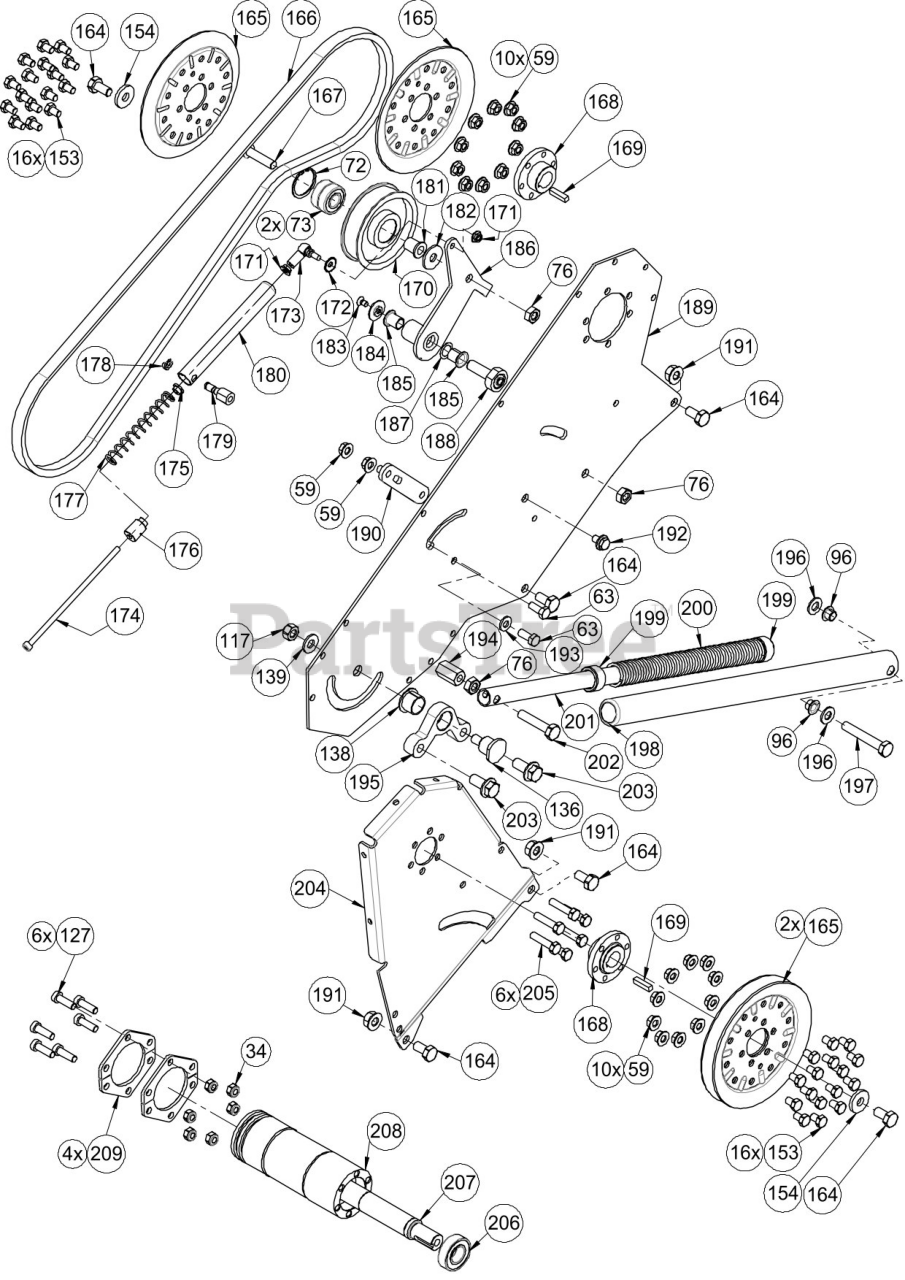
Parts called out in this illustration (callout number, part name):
34	NUT, LK-NYL M8 DIN 985 8 ZCC
59	NUT, FLG SLF LK M8 CL 8 ZCC
63	BLT, HEX M8X20 DIN 933 8.8
72	RG, RTNG-INT .35X1.5 DIN 472
73	BRG,BALL 6202-2RSH (15X35X11)
76	NUT, HEX M10 DIN 934 8 ZCC
96	BHSG, DU FLG BB1009DU
117	NUT, LK V-M10 DIN 980
127	TORX SHCS M8X25 SIMILAR TO DIN 7984 8.8
136	SCREW, COLLAR
138	BHSG, DU FLG BB201DU
139	WHSR, BLVL M10 DIN 6796
153	BLT, HEX M8X12 DIN 933 8.8 ZCC
154	WSHR, FLT M10.5 DIN 6340 ZCC
164	BLT, HEX M10X20 DIN 933 8.8 ZCC
165	HALF, PULLEY
166	V-BELT, PTO - INTERMEDIATE
167	SCR, BHC M10X40 ISO 7380
168	HUB, PULLEY
169	KEY, 6MM SQ X 25MM
170	PULLEY, IDLER
171	NUT, FLG M6 DIN 6923 8 ZCC
172	WSHR, LK EDGE F M6
173	JOINT, BALL
174	SCR, SKH M6X160 8.8 ZCC
175	BSHG, DU FLG BB 061006
176	GUIDE, COMP. SPRING
177	SPRING, COMPRESSION
178	RETAINER, KL 8 MBO 09
179	FOLLOWER, LONG
180	SLEEVE, SPRING
181	BUSHING, SLEEVE
182	WSHR, FLT M10.5 DIN 9021 ZCC
183	TORX FHCS M6X10 8.8 ZCC
184	WASHER, SPECIAL
185	BSHG, DU FLG BB 1207 DU
186	ASSY, IDLER ARM
187	WSHR, FLT M14 DIN 988
188	SPACER, IDLER MOUNT
189	PLATE, IDLER MOUNT
190	LEVER, SPRING TENSION
191	NUT, FLG SLF LK M10 CL 8 ZCC
192	BLT, SER FLG M8X12 VERBUS RIPP BK
193	WSHR, FLT M8.4 DIN 134 ZCC
194	NUT, COUPLING M10 DIN 6334 ZCC
195	BRKT, PIVOT
196	WSHR, FLT A M10.5 DIN 125 ZCC
197	BLT, HEX M10X65 DIN 931 10.9 (BLK)
198	SLEEVE, SPRING
199	GUIDE, SPRING
200	SPRING, COMPRESSION
201	TUBE, SPRING
202	BLT, HEX M10X50 DIN 931 8.8 ZCC
203	BLT, SER FLG M12X25 VERBUS RIPP 100
204	PLATE, SPINDLE MOUNT
205	BLT, HEX M8X35 DIN 933 8.8 ZCC
206	BRG,BALL .6004-2RSH (20X42X12)
207	SPINDLE, PULLEY
208	HOUSING, SPINDLE
209	BRACKET, SPINDLE MOUNT
